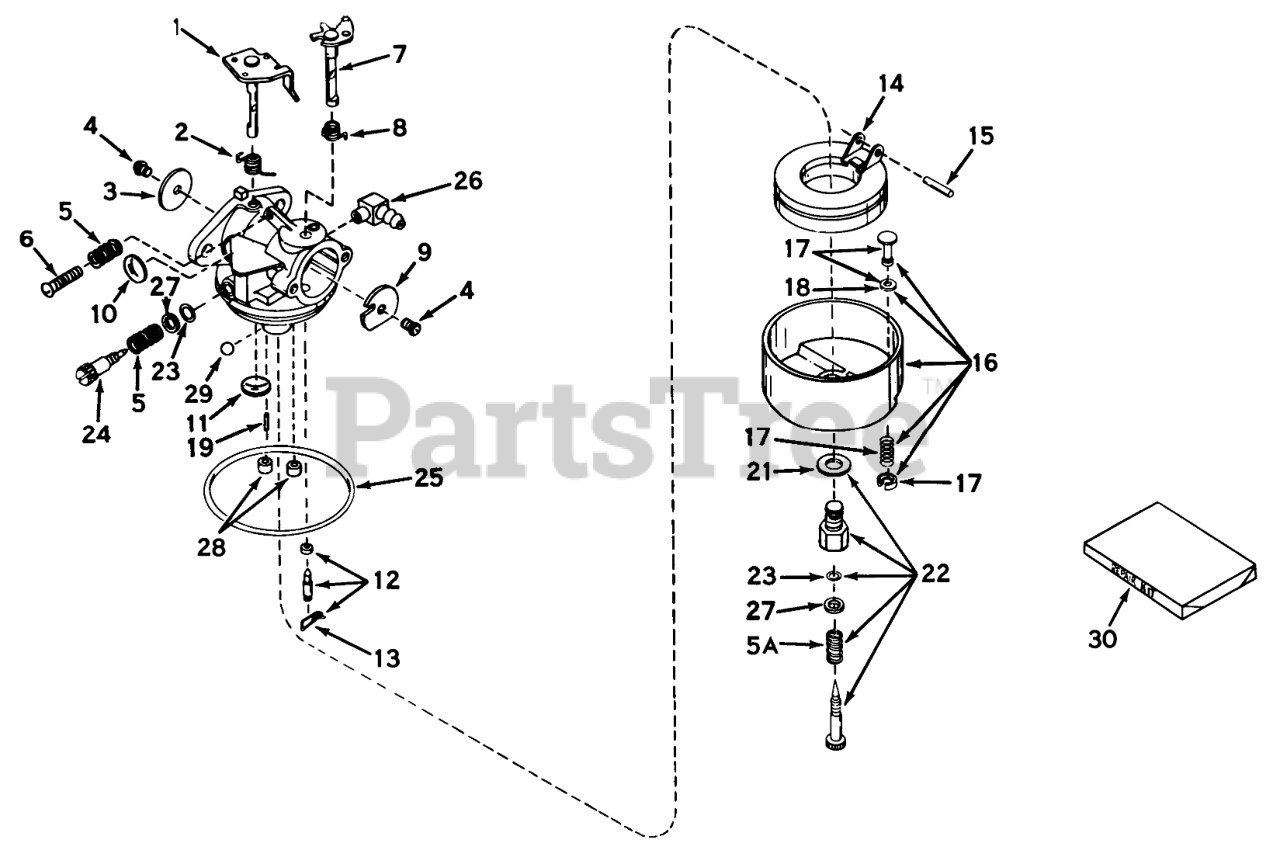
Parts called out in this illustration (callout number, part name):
1	Shaft & Lever Assy.
2	Spring, Throtte Return
3	Shutter-Throttle
4	Screw-Shutter
5	Spring-Tension
6	Screw-Throttle Crack Screw / Idle Speed
7	Shaft& Lever Assy., Choke
8	Spring, Choke return
9	Shutter, Choke
10	Plug-Welch, Idle Mixture Well
11	Plug-Welch, Atmospheric Vent
12	Inlet Needle, Seat & Clip Assy. (Incl. #13)
13	Clip-Spring
14	Float,Carburetor
15	Shaft-Float
16	Bowl & Drain Assy., Float (Incl. #17
17	Plunger Assy., Drain (Incl. No. 18)
18	Gasket-Plunger, Drain
21	Washer-Bowl Nut
22	Adjustment Screw Assy., Main (Incl. Nos. 5A, 21, 23 & 27)
23	"O"Ring
24	Screw, Idle Adj.
25	O Ring-Bowl, Float
26	Fitting Fuel Inlet
28	Plug, Cup
29	BalI, Steel
30	Repair Kit (Incl. Items Marked )
